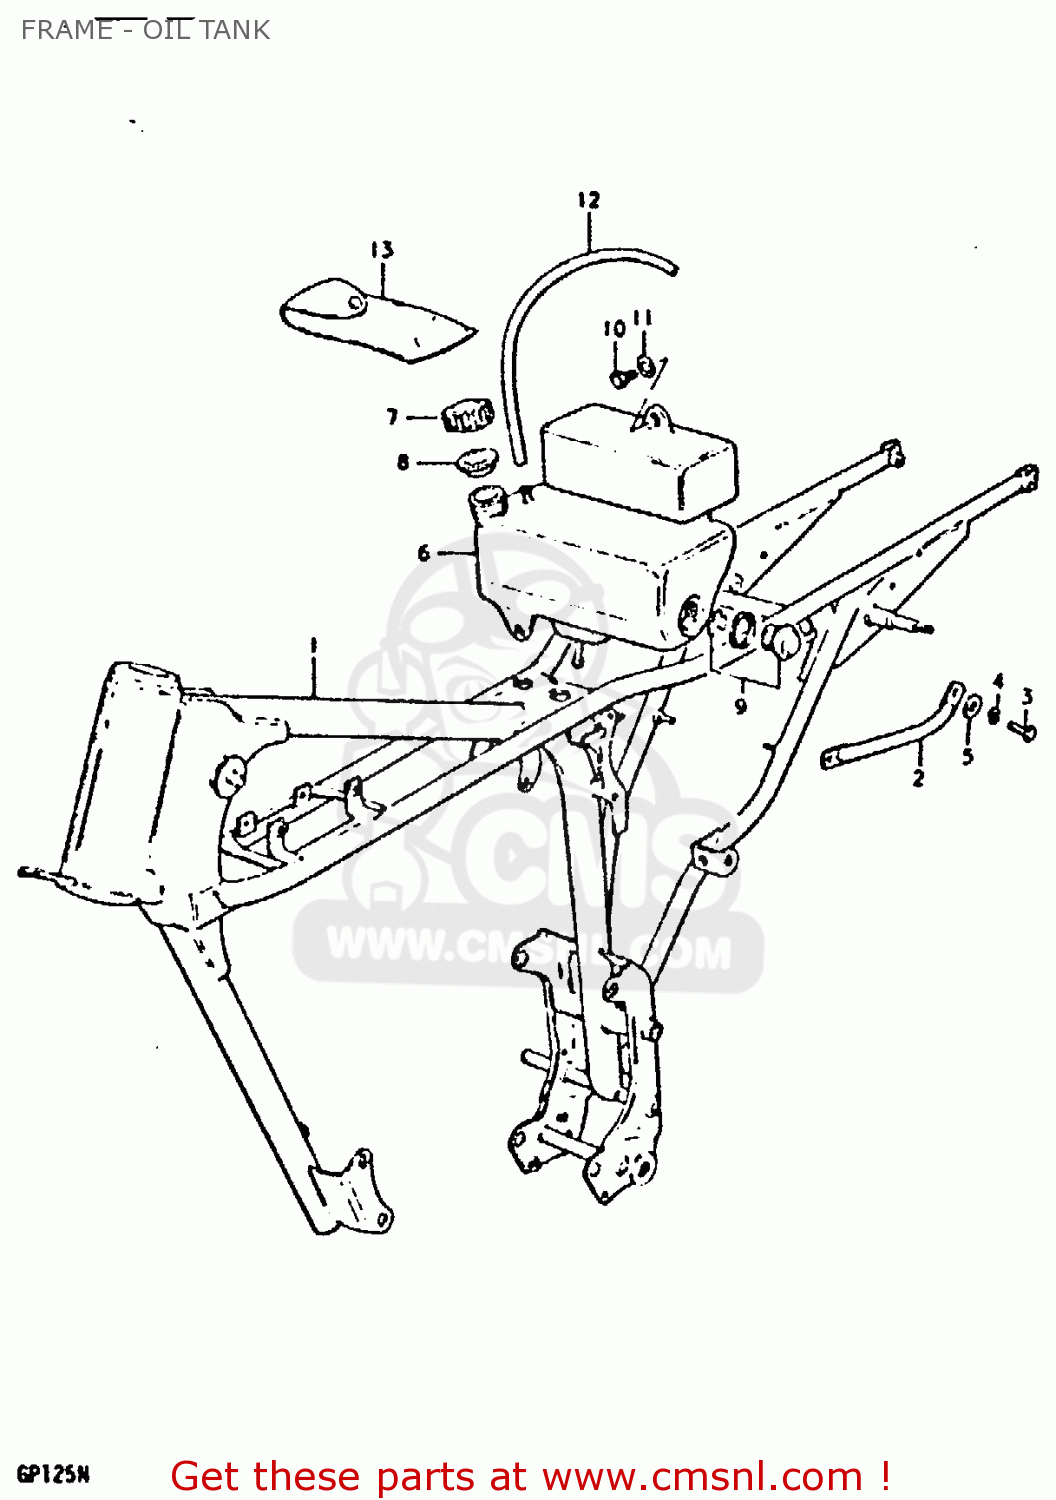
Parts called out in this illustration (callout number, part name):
1	FRAME
6	TANK,OIL
7	CAP,OIL TANK
8	GASKET,OIL TANK CAP (NAS)
9	LENS SET,OIL LEVEL
10	BOLT, UPPER
11	WASHER
12	HOSE
13	TOOL SET
